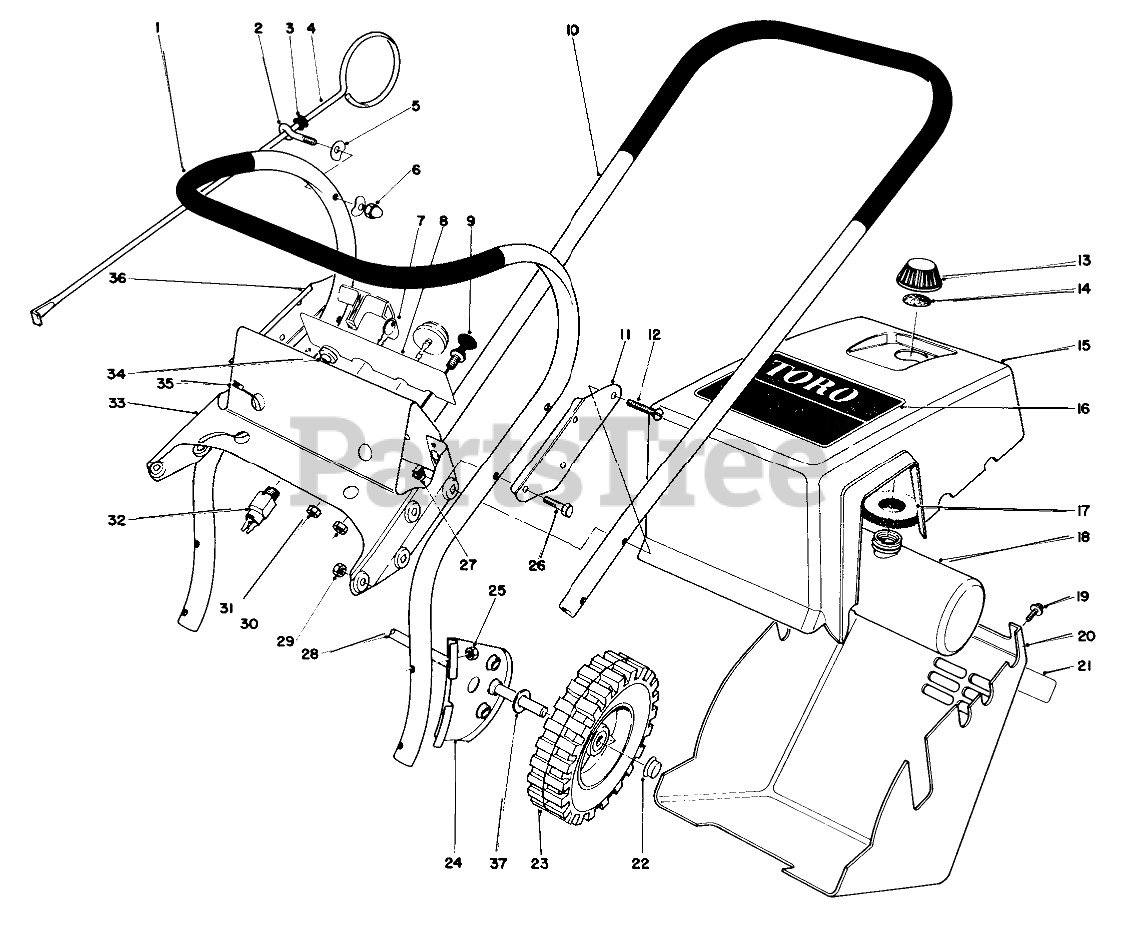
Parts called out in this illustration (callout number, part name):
1	LOWER HANDLE
2	Bolt-Eye
3	GROMMET
4	Vane Adj. Rod
5	WASHER
6	NUT-CAP
7	Key
8	Decal Control Panel
9	CHOKE CONTROL
10	Upper Handle
11	SPLICE PLATE
12	Sems Mach. Screw
13	Gas Cap Assy. (Incl. Ref. #14)
14	GAS CAP GASKET
15	Shroud (Incl. Ref. #16)
16	Decal-Toro
17	FOAM PAD
18	Gas Tank Assembly (Incl. Ref. #13 & 14)
19	SCREW
20	Lower Shroud (Incl. Ref. #21)
21	Decal-Instruction
22	RETAINER-PUSH ON
23	WHEEL
24	WHEEL BRKT B
25	NUT-HEX
26	SCREW-HH
27	Nut Retainer
29	NUT-LOCK, CONE
30	PAL NUT/CHOKE CNTRL
31	NUT-KEPS
32	SWITCH-ON / OFF
33	Tank Support & Control Panel (Incl. Ref. #8)
34	GUIDE-ROPE, STARTER
35	Strap
36	Plate-Splice
37	WASHER-FLAT
